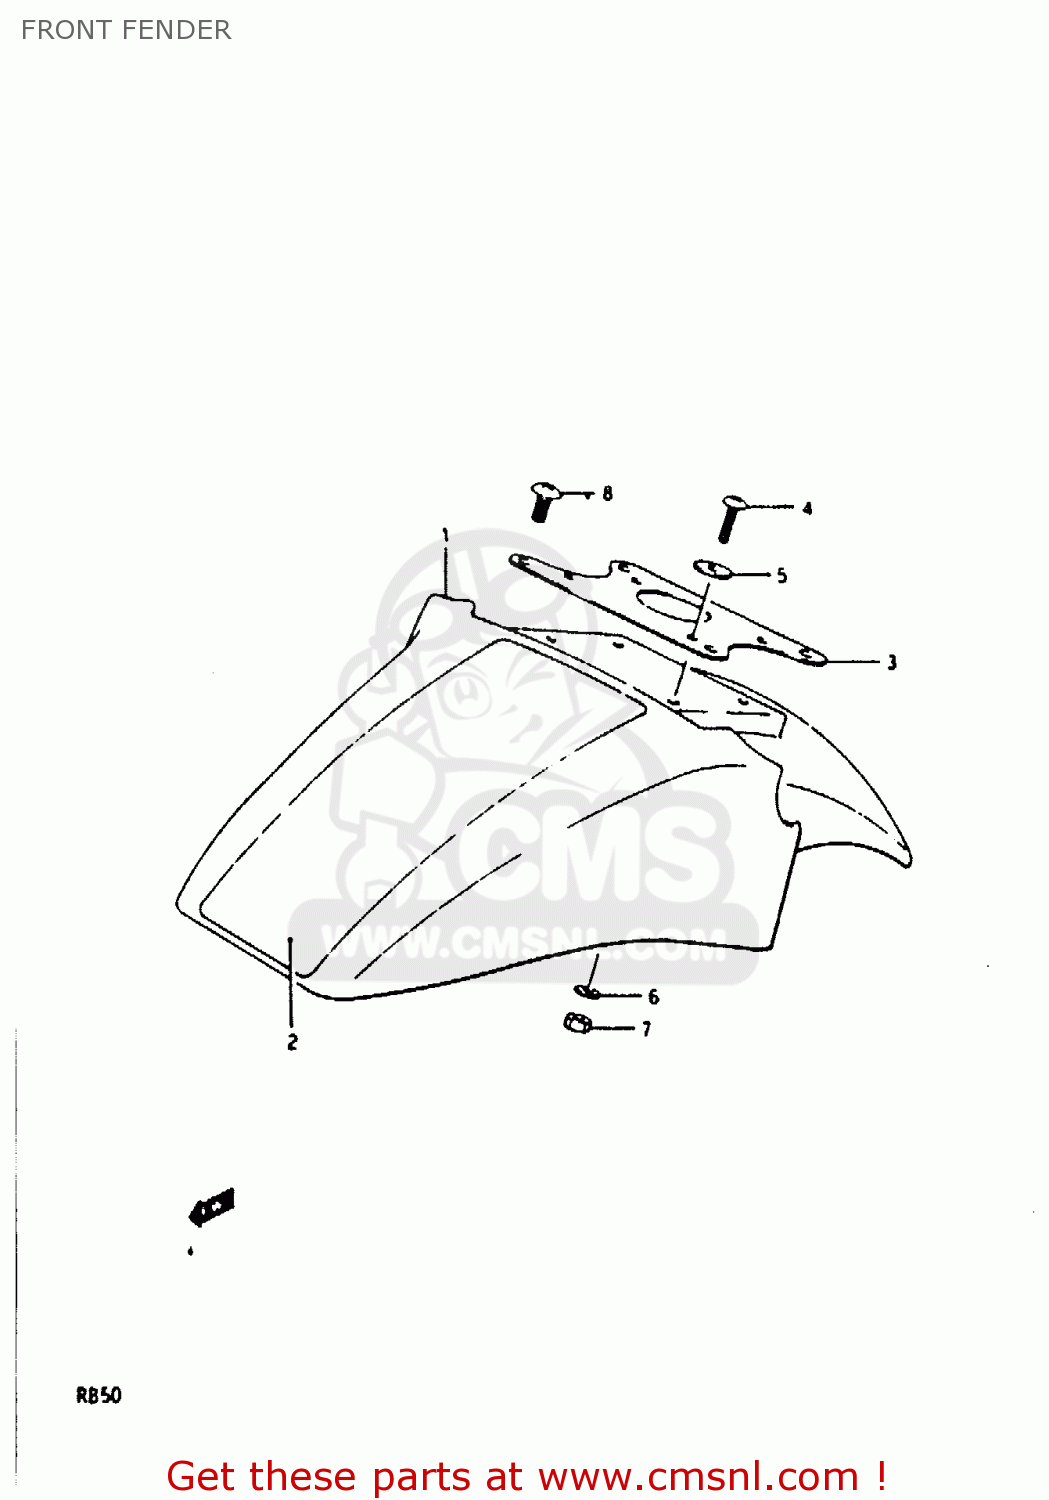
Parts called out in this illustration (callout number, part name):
1	FENDER,FR
3	BRACE,FR FENDER
4	SCREW
5	WASHER (5.5X18X1)
6	LOCK WASHER
7	NUT
8	SCREW 6X12
